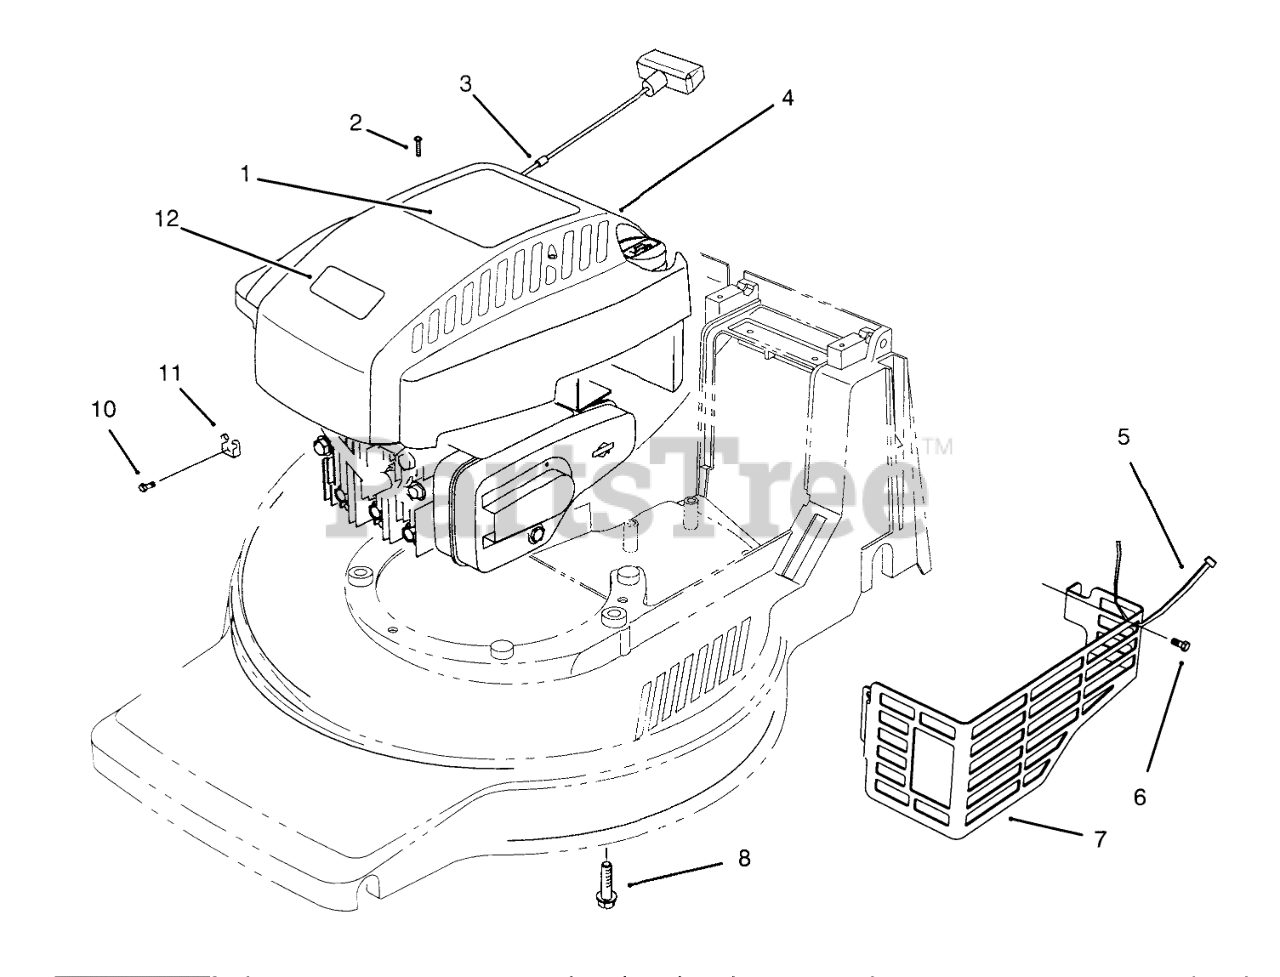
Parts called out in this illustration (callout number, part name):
1	DECAL - SHROUD
2	SCREW-PPH
3	STOP-ROPE
4	SHROUD-ENGINE
5	TIE-CABLE
6	SCREW-HWH
7	SHIELD-MUFFLER
8	SCREW-HWH
10	SCREW-CLAMP
11	CLAMP-CASING
12	PLATE-LOGO
